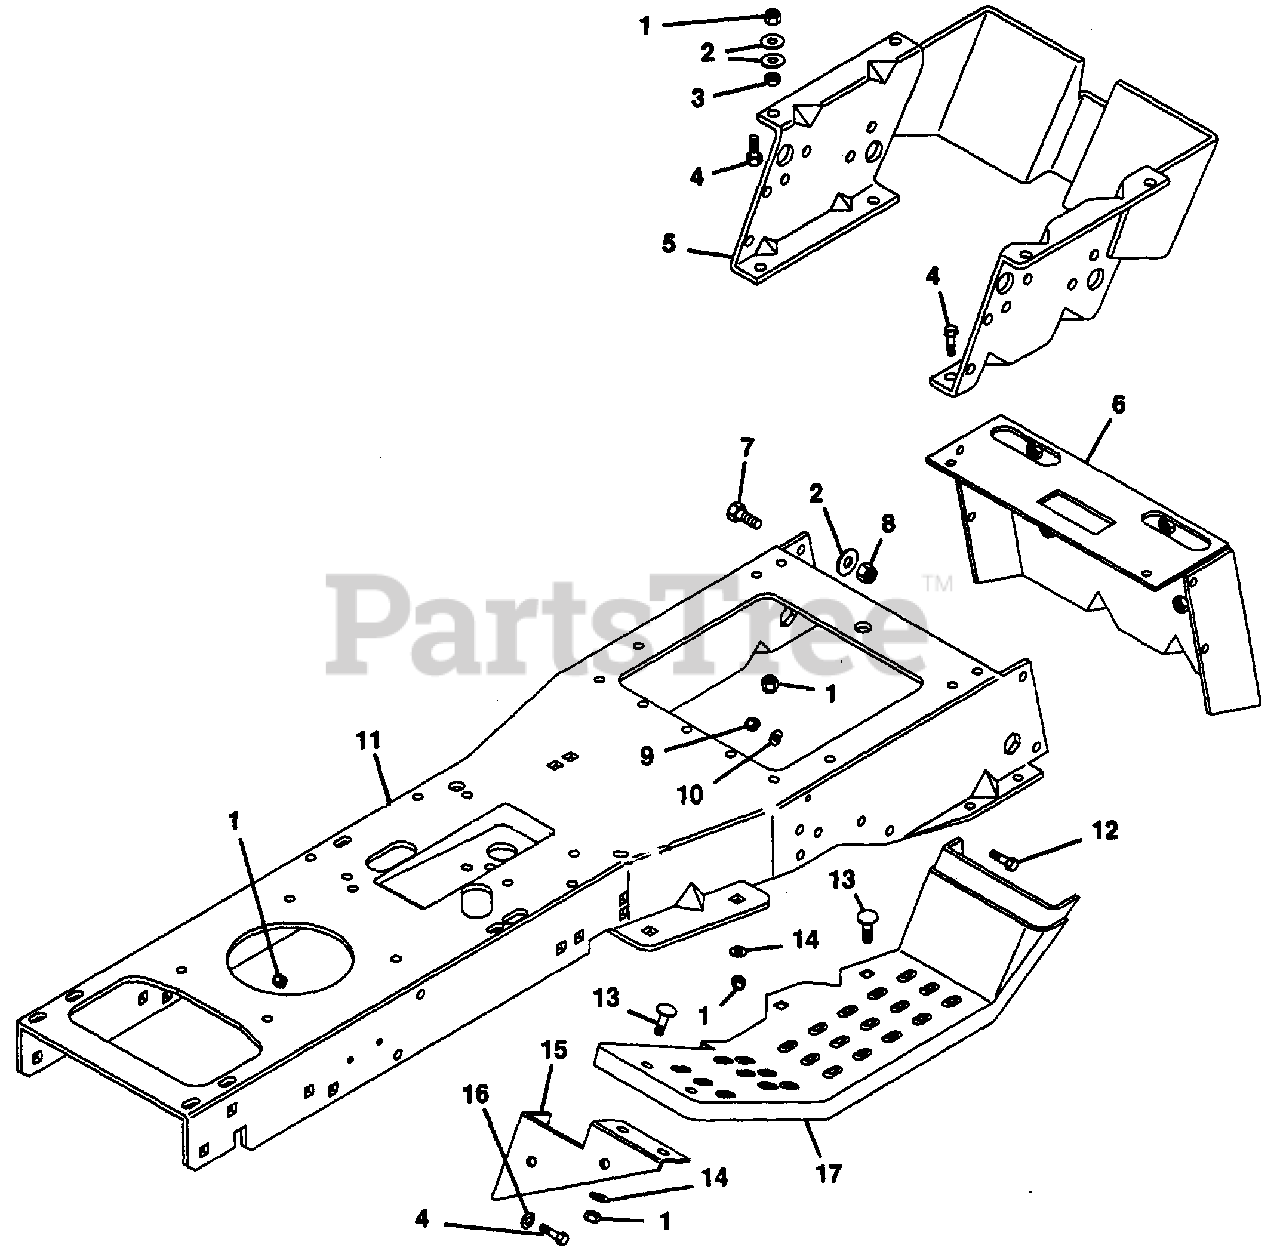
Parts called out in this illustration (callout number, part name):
1	Nut, Lock 5/16-18
2	Washer, Flat .375 x 1.125 x .065
3	Nut, Hex 5/16-18
4	Bolt, Hex 5/16-18 x 1.00
5	Deck, Support
6	Weldment, Tailboard
7	Bolt, Hex 3/8-16 x .875
8	Nut, Lock 3/8-16
9	Nut, Lock 1/4-20
10	Washer, Flat .281 x .625 x .065
11	Frame
12	Bolt, Hex 1/4-20 x .750
13	Bolt, Carriage 5/16-18 x 1.0
14	Washer, Flat .344 x .688 x .065
15	Foot Rest Brace, L.H.
15	Foot Rest Brace, R.H.
16	Washer, Flat .313 x .875 x .065
17	Foot Rest, L.H.
17	Foot Rest, R.H.
NS	Decal, Transmission Lockout
NS	Decal, Caution
